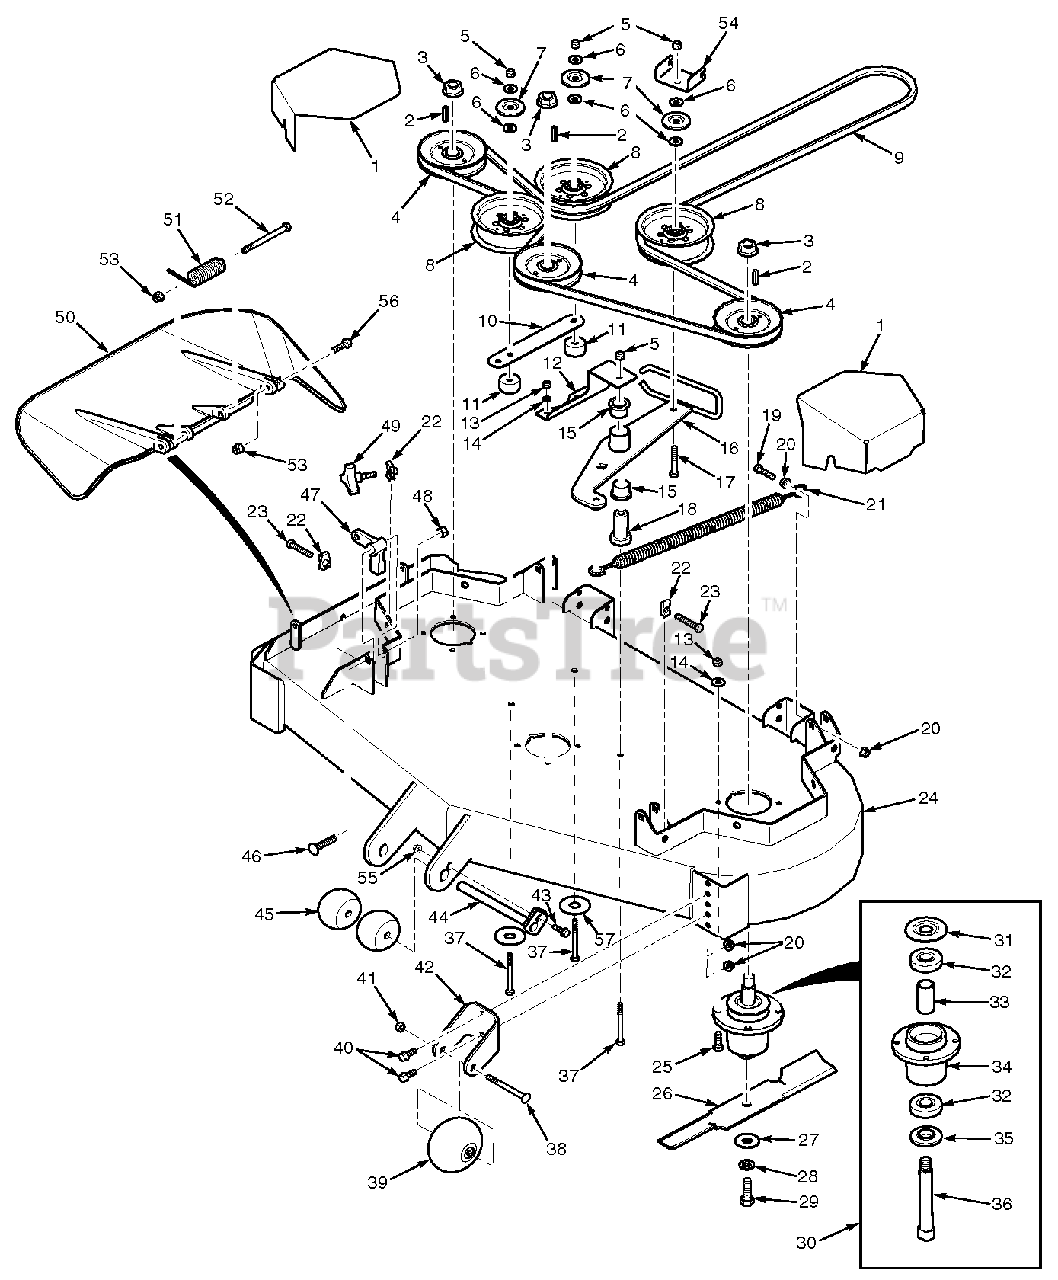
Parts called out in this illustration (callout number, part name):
1	Belt Cover
2	Key, 1/4 x 1/4 x 1-1/4"
3	Nut, 3/4-16 Spiral Lock
4	Pulley, 5.13" OD - 25mm Bore
4	Pulley, 5.73" OD - 25mm Bore
4	Pulley, 6.32" OD - 25mm Bore
5	Nut, Elastic Stop 3/8-16
6	Flatwasher, 3/8-.391 x .938 x .105
7	Dust Shield
8	Pulley, 5" Idler
9	Belt, Cutter Deck
10	Brace, Pulley
11	Spacer
12	Support, Idler Pivot
13	Nut, Elastic Stop
14	Lockwasher, 5/16 Spring
15	Bearing
16	Idler Arm
17	Bolt, Hex Head 3/8-16 x 2-1/2"
18	Pivot, Idler
19	Bolt, Hex Head 3/8-16 x 1-1/2 Gr.8
20	Nut, Serrated Flange 3/8-16
21	Spring, Idler
22	U-Nut, 3/8-16
23	Bolt, Hex Head 3/8-16 x 2" Special Lock
24	Cutter Deck w/Decals
25	Bolt, Hex Head 5/16-18 x 1-1/2"
26	Cutter Blade, 16-1/2"
26	Cutter Blade, 18"
27	Flatwasher, 5/8-.688 x 1.75 x .134 HD
28	Lockwasher, 1/2 Spring
29	Bolt, Hex Head 5/8-11 x 1-1/2"
30	Spindle Assembly
31	Debris Shield
32	Bearing
33	Spacer
34	Spindle Housing Assembly
35	Protector, Bearing
36	Shaft, Spindle
37	Bolt, Hex Head 3/8-16 x 3-1/2"
38	Bolt, Carriage 3/8-16 x 4"
39	Wheel, Anti-Scalp
40	Bolt, Hex Head 3/8-16 x 1" Ser. Flg.
41	Nut, Center Lock 3/8-16
42	Bracket, Anti-Scalp
43	Bolt, Hex Head 5/16-18 x 1"
44	Shaft Weldment
45	Wheel, Anti-Scalp
46	Bolt, Carriage 7/16-14 x 2-1/4"
47	Lever, Deck Level
48	Nut, Elastic Stop 7/16-14
49	Knob w/Stud
50	Discharge Chute Assy.
51	Spring, Discharge Chute
52	Bolt, Hex Head 5/16-18 x 4-3/4"
53	Nut, Elastic Stop 5/16-18
54	Bracket, Belt Guide
55	Nut, Serrated Flange 5/16-18
56	Bolt, Hex Head 5/16-18 x 1-3/4"
57	Flatwasher, 3/8-.406 x 2.25 x .1875
